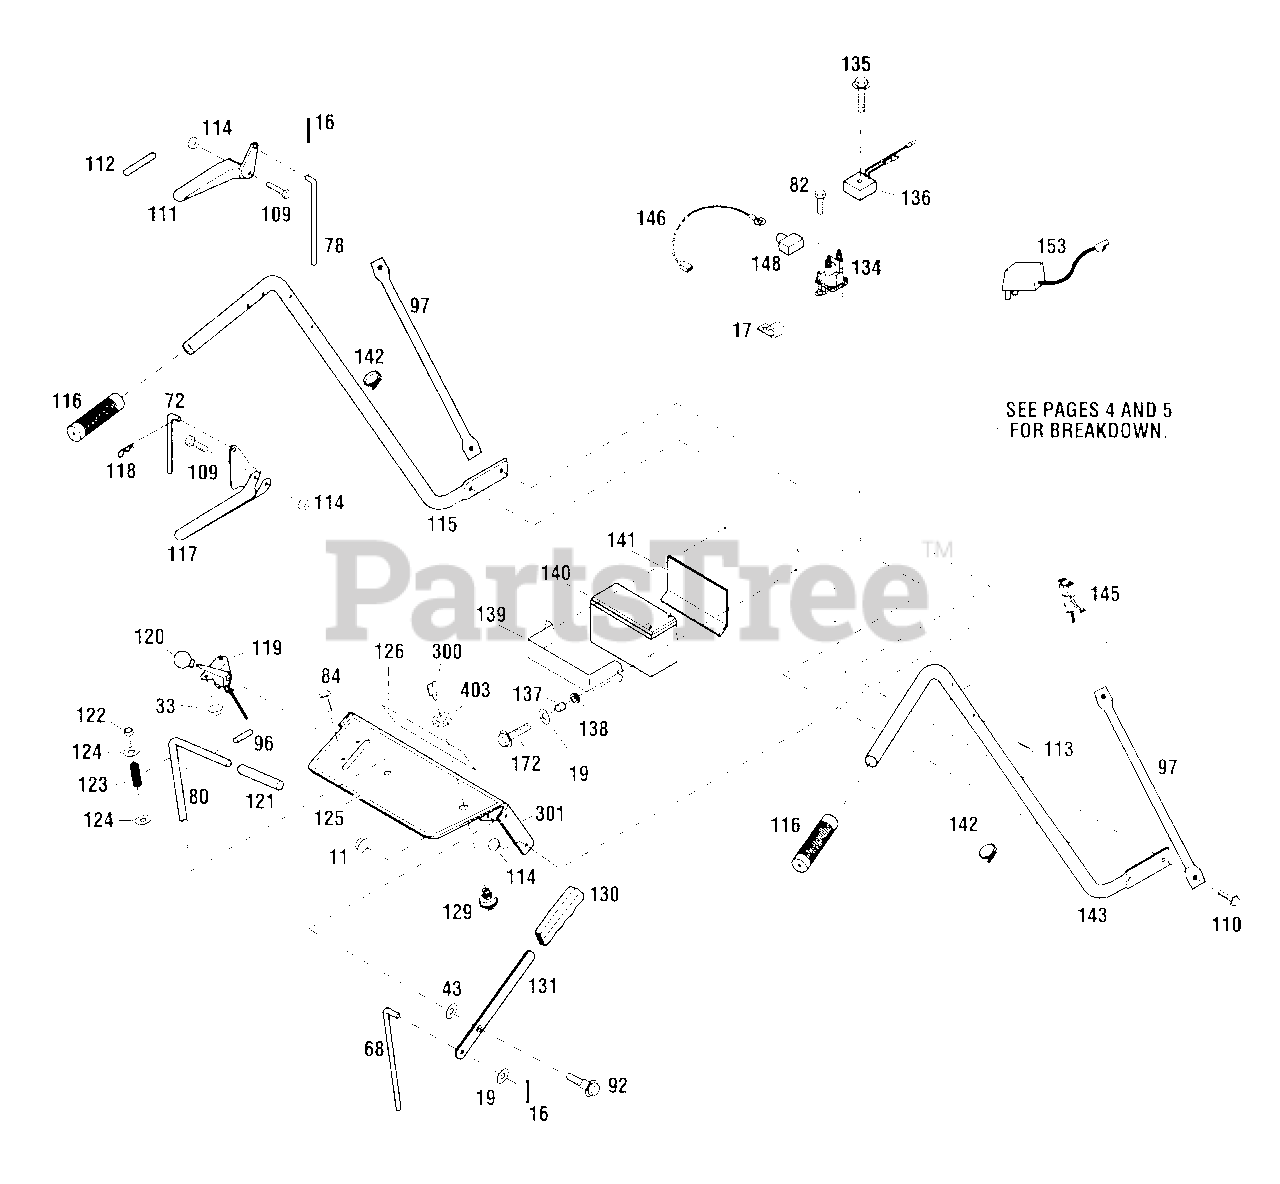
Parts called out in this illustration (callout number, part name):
11	Flange Locknut, 3/8-16
16	Cotter Pin, 3/32 x 5/8
19	Flat Washer, 5/16
33	Flange Locknut, 1/4-20
43	Flat Washer, 1/2
68	Upper Blade Rod
72	Upper Transmission Rod
78	Upper Brake Rod
80	Shift Rod
82	Thread Cut. Screw, 1/4-20 x 1/2
84	Flange Lock Screw, 1/4-20 x 1/2
92	Shoulder Bolt
96	Roll Pin, 1/4 x 2-1/4
97	Brace, Handlebar
109	Hex Screw, 1/4-20 x 1-3/4
110	Flange Lock Screw, 5/16 x 3/4
111	Control Handle
112	Operator Presence Control Decal
113	Hex Screw, 1/4-20 x 1-3/4, Grade 8
114	Locknut, 1/4-20
115	Left Handlebar
116	Handle Grip
117	Control Handle
118	Hair Pin, 5/64
119	Throttle Control
120	Knob
121	Handle Grip
122	Nylon Bushing
123	Compression Spring
124	Flat Washer, 1/2
125	Warning Decal
126	Logo Decal
129	Ignition Switch
130	Handle Grip
131	Mower Engage Lever
134	Solenoid
135	Thread-Cut. Screw, 1/4-20 x 1-1/2
136	Regulator
137	Spacer
138	Grommet
139	Battery Bracket
140	Battery
141	Battery Pad
142	Plastic Tie
143	Right Handlebar
145	Wiring Harness
146	Wire Lead
148	Boot
153	Battery Charger
172	Screw, 5/1 6-18 x 3/4"
300	Ignition Key
301	Console Assembly
403	Nut, Ignition Switch
